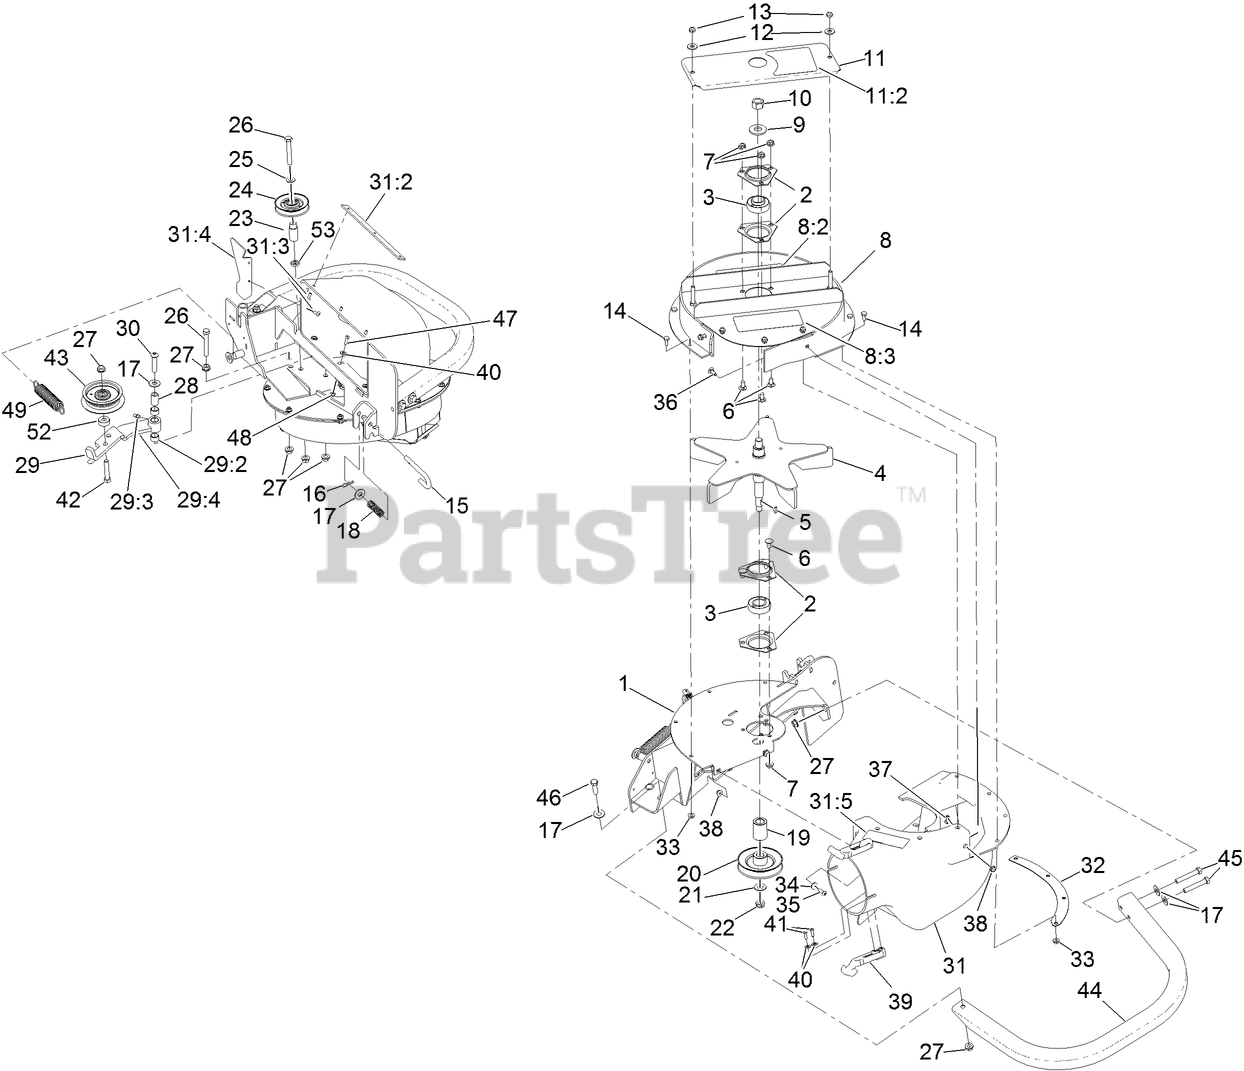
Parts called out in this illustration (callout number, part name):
1	MOUNT-BLOWER [BLACK]
2	HOUSING-FLANGE
3	BEARING
4	IMPELLER
5	KEY-WOODRUFF
6	SCREW-CARR
7	NUT-HF
8	UPPER-HOUSING W/DECALS
8:2	DECAL-WARNING
8:3	DECAL - E-Z VAC
9	WASHER-SPRING
10	NUT-HEX
11	COVER-BEARING W/DECAL
11:2	DECAL-WARNING
12	WASHER-FLAT
13	NUT-LOCK, NI
14	SCREW-HH
15	PIN-LATCH
17	WASHER-FLAT
18	SPRING-COMPRESSION
19	SPACER
20	PULLEY
21	WASHER-FLAT
22	NUT-LOCK, NI
24	IDLER-INSIDE
25	WASHER-FLAT
26	SCREW-HH
27	NUT-HHF, WHIZ
28	BUSHING-PIVOT, IDLER
29	IDLER ARM ASM W/BUSHINGS
29:2	BUSHING
29:3	FITTING-GREASE
29:4	DECAL-WARNING
30	SCREW-HSBH
31	BLOWER CHUTE ASM
31:2	PLATE-REINFORCEMENT
31:3	RIVET-BLIND
31:4	PLATE-FILLER
31:5	DECAL-WARNING
32	PLATE-BACKING, BLOWER
33	NUT-HF
34	WASHER-FLAT
35	SCREW-HSBH
36	BOLT-CARR
37	SCREW-CARR
38	NUT-HF
39	LATCH-RUBBER
40	WASHER-FLAT
41	SCREW-HSBH
42	SCREW-HH
43	IDLER-FLAT
45	SCREW-HH
46	SCREW-HH
47	SCREW-HSBH
48	NUT-LOCK, NI
49	SPRING-EXTENSION
52	SPACER
53	SPACER
